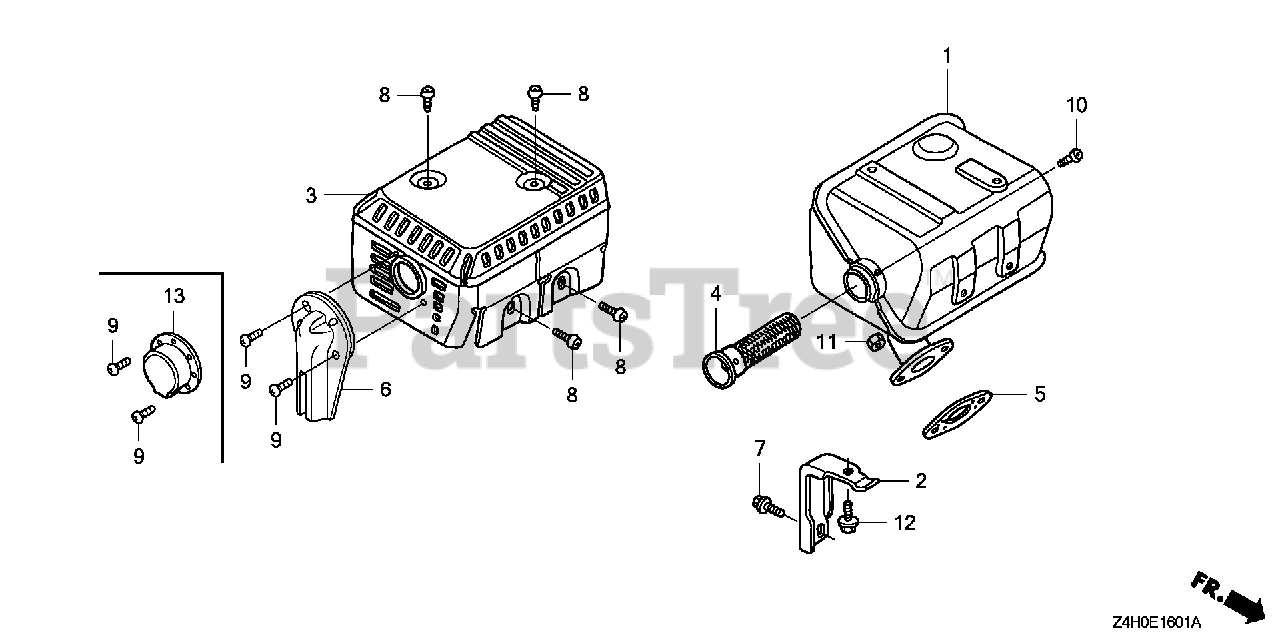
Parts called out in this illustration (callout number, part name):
1	MUFFLER (SILENT)
1	MUFFLER (ARRESTER) (SPARK ARRESTER TYPE)
2	STAY, MUFFLER
3	PROTECTOR, MUFFLER (SILENT)
4	ARRESTER, SPARK
4	ARRESTER, SPARK (SILENT)
5	GASKET, MUFFLER
6	DEFLECTOR, MUFFLER
7	BOLT, FLANGE (6X13)
8	SCREW, TAPPING (5X8)
9	SCREW, TAPPING (4X6) (TO INSTALL OPTIONAL SPARK ARRESTER)
10	SCREW, TAPPING (4X6) (TO INSTALL OPTIONAL SPARK ARRESTER)
10	SCREW, TAPPING (4X6)
11	NUT, HEX. (8MM)
12	BOLT, FLANGE (6X12) Use up to Engine SN 1543277.
